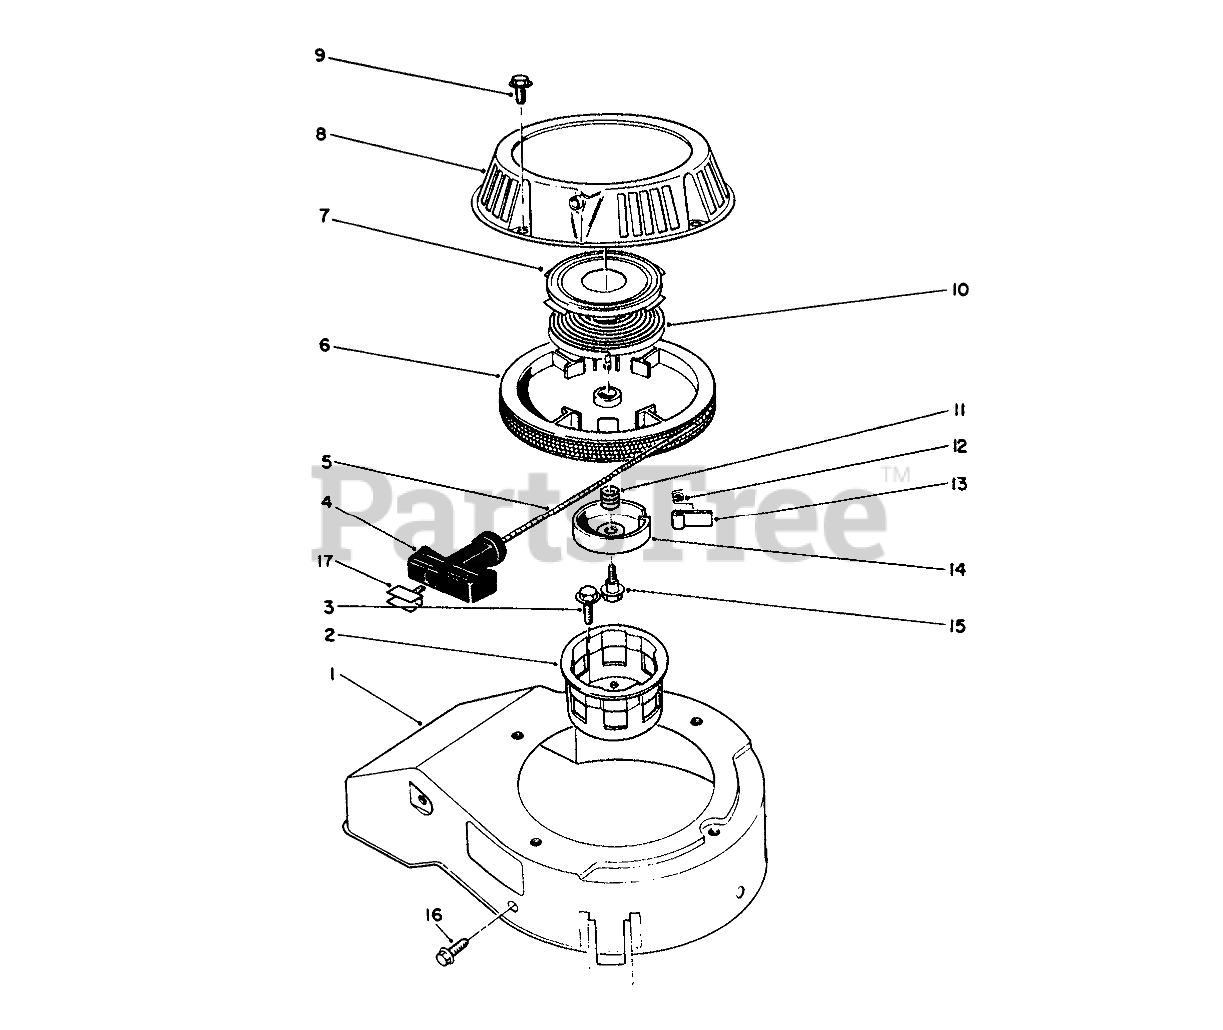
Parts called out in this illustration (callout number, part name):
1	COVER
2	CUP - STARTER
4	HANDLE-RECOIL
5	ROPE-STARTER
7	Retainer-Recoil Spring
9	SCREW-HHF
10	Spring-Recoil
11	SPRING
12	SPRING
14	RETAINER
17	Insert Handle
